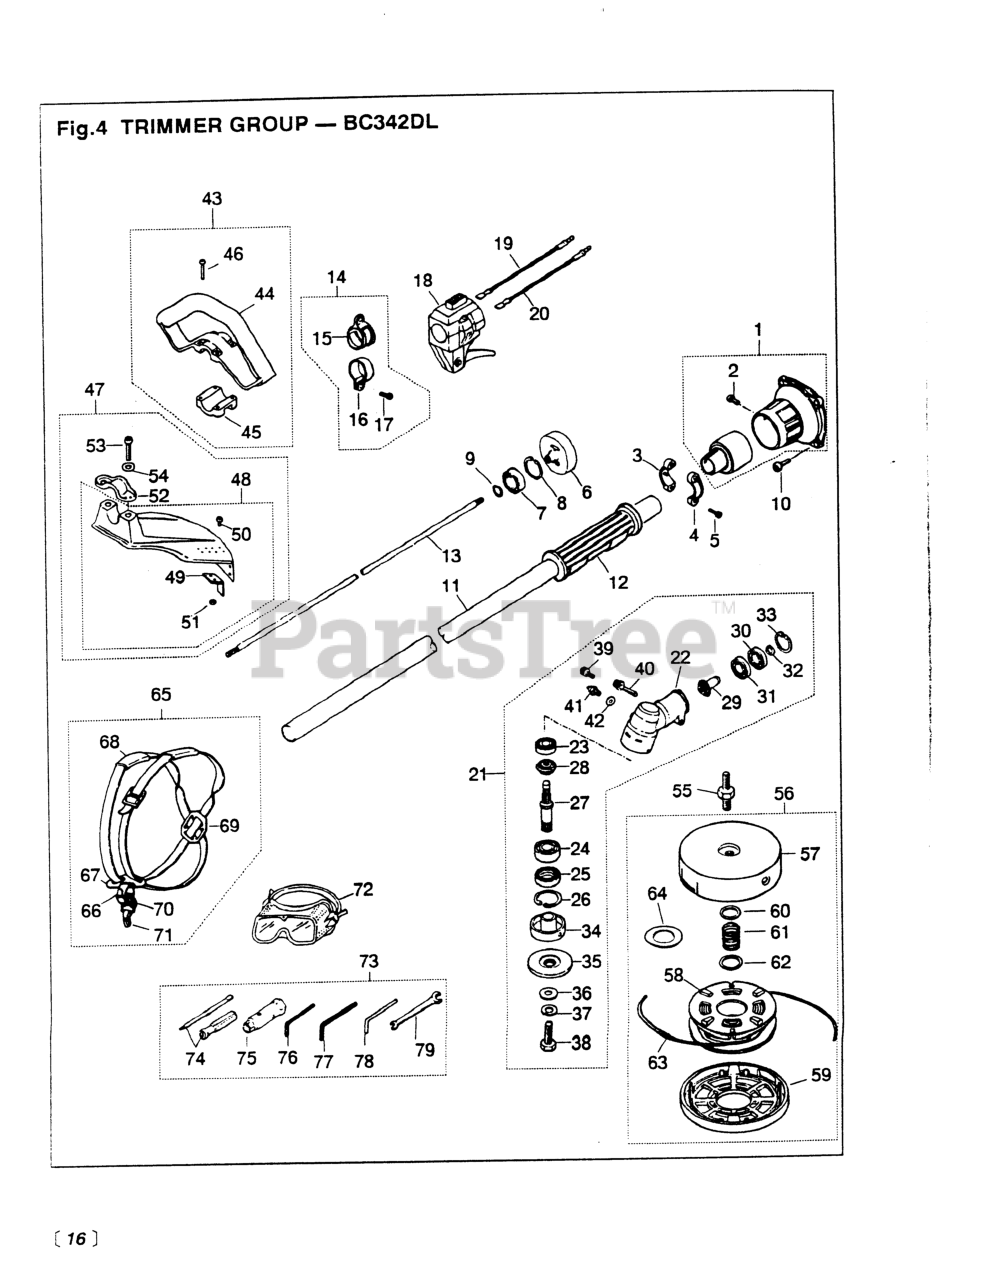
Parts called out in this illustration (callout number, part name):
1	HOUSING ASSY (RPLS-11100)
2	SCREW, M6 x 10
3	CLAMP, RIGHT (RPLS -11130)
4	CLAMP, LEFT (RPLS-11140)
5	BOLT
6	DRUM, CLUTCH
7	BEARING
8	RING, SNAP, M35 X 1.5
9	RING, SNAP, M15 X 1.0
10	BOLT, M6 X 20
13	SHAFT, SPLINE
14	HANGER ASSY. (NLA)
15	HANGER
16	CLAMP
17	SCREW, M5 x 25
19	CORD-A, BLACK
20	CORD-B, RED
21	GEARCASE (RPLS-13005)
22	GEARCASE (RPLS -13113)
23	BEARING (RPLS T3403-13510)
25	SEAL, OIL
26	RING, SNAP, M32 x 1.2
27	SHAFT, GEAR
28	GEAR, BEVEL
31	BEARING (RPLS T3403-13510)
32	RING, SNAP
34	HOLDER (A)
35	HOLDER (B)
36	WASHER, M8 x 2.3 (RPLS -20823)
37	WASHER (RPLS 3180-13270)
38	BOLT, LH
39	BOLT, M5 X 10
40	BOLT, M6 x 1.35
41	FITTING, GREASE
42	WASHER, M6 X .8
43	HANDLE ASSEMBLY
44	HANDLE
45	CLAMP
46	SCREW, M5 x 30
47	GUARD ASSY (RPLS -24001)
48	GUARD COMP.
49	BLADE
50	SCREW, M5 x 12
51	NUT
52	CLAMP
53	BOLT, M6 x 1.30
54	WASHER, M6 X 15
55	ARBOR, 8MM
56	6
59	COVER
60	PLATE, LARGE
62	PLATE, SMALL
63	CORD
64	SPACER
68	PROTECTOR
73	TOOL SET
74	SCREWDRIVER
76	WRENCH (TOOL)
77	WRENCH (TOOL)
78	BAR
79	SPANNER, 8 X 10 (RPLS 2540- )
